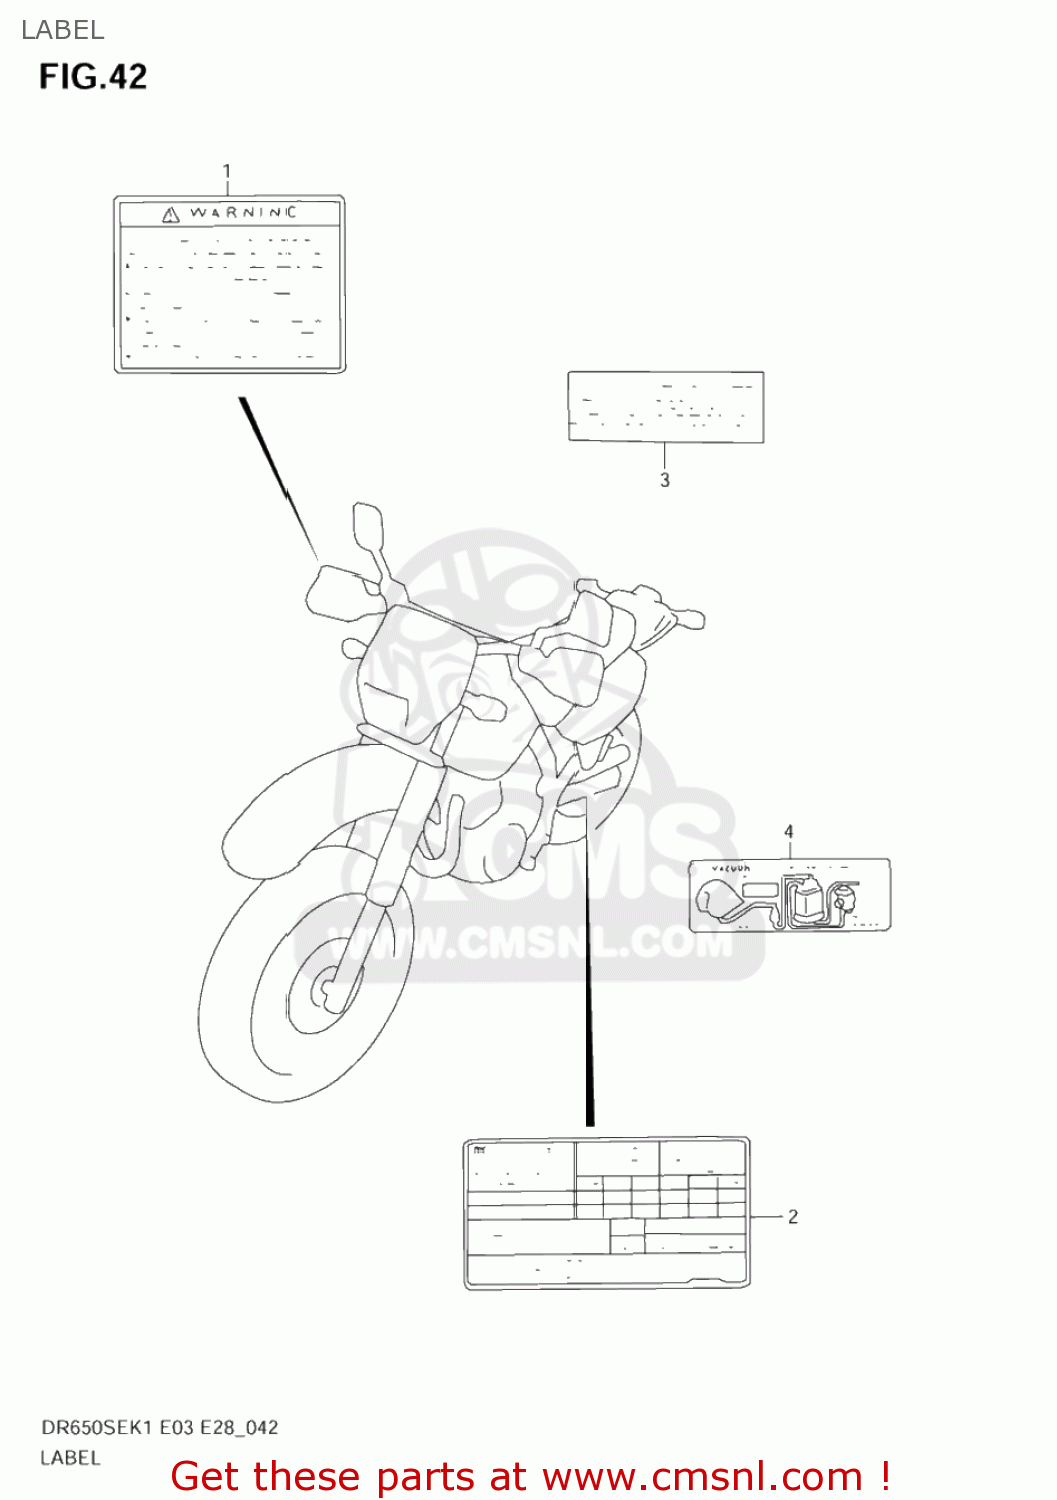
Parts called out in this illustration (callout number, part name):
1	LABEL,GENERAL WARNING
2	LABEL (TIRE INFORMATION)
3	LABEL,MANUAL NOTICE
4	LABEL,PIPING DIAG
5	MANUAL,OWNER'S
6	LABEL,STARTING CAUTION
